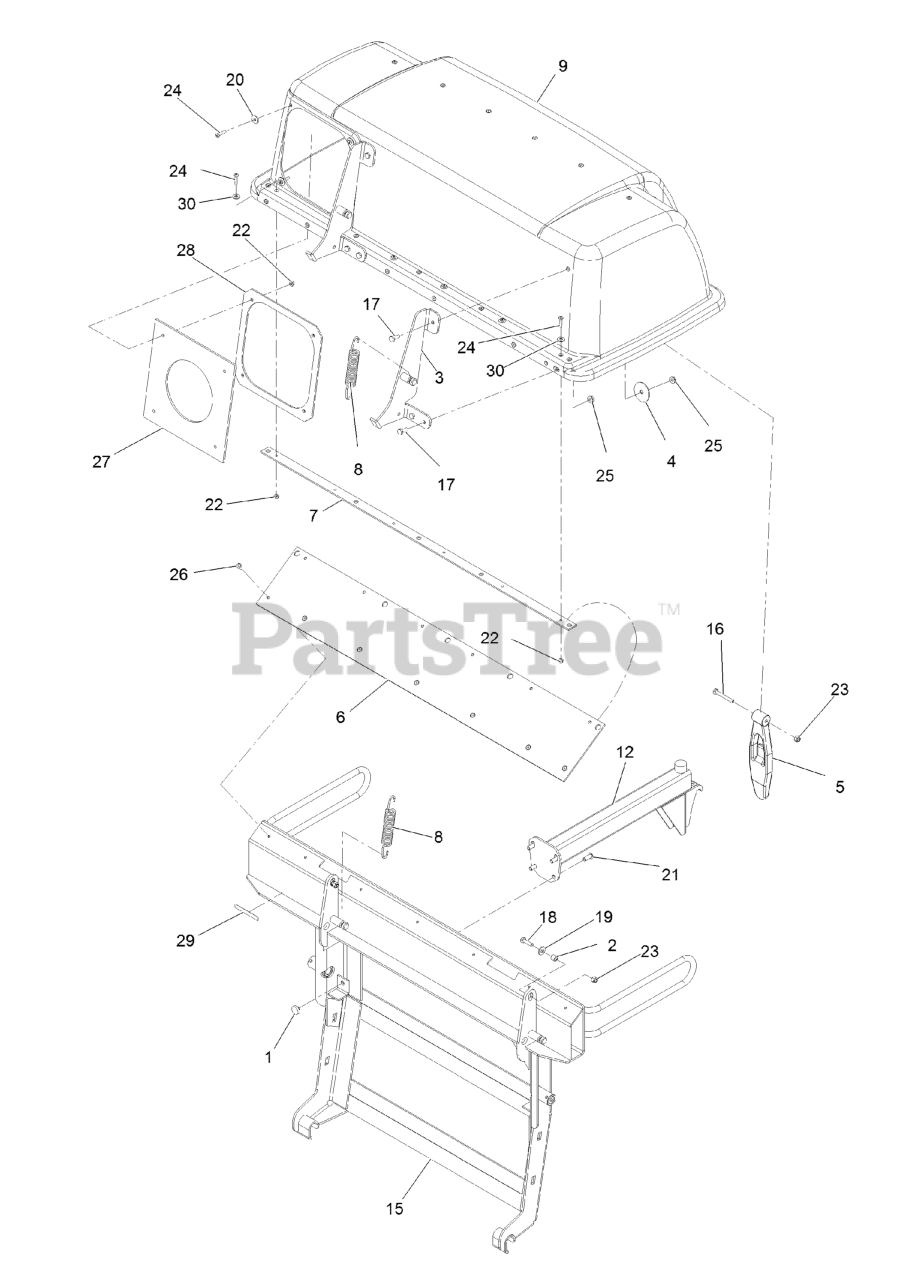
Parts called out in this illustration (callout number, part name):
3	HINGE ASM
7	PLATE-BACKING
8	SPRING-EXTENSION
9	ASM, HOOD
12	BAG SUPPORT ASM
15	FRAME-BAG, TWIN
16	SCREW-HH
17	SCREW-HH
18	SCREW-HH
19	WASHER-FLAT
20	WASHER-FLAT
21	SCREW-HSBH
22	NUT-LOCK, NI
23	NUT-LOCK, NI
24	SCREW-PPH
26	RIVET-BLIND
27	SEAL-CHUTE
28	CLAMP-SEAL
29	DECAL-WARNING
30	WASHER-FLAT
